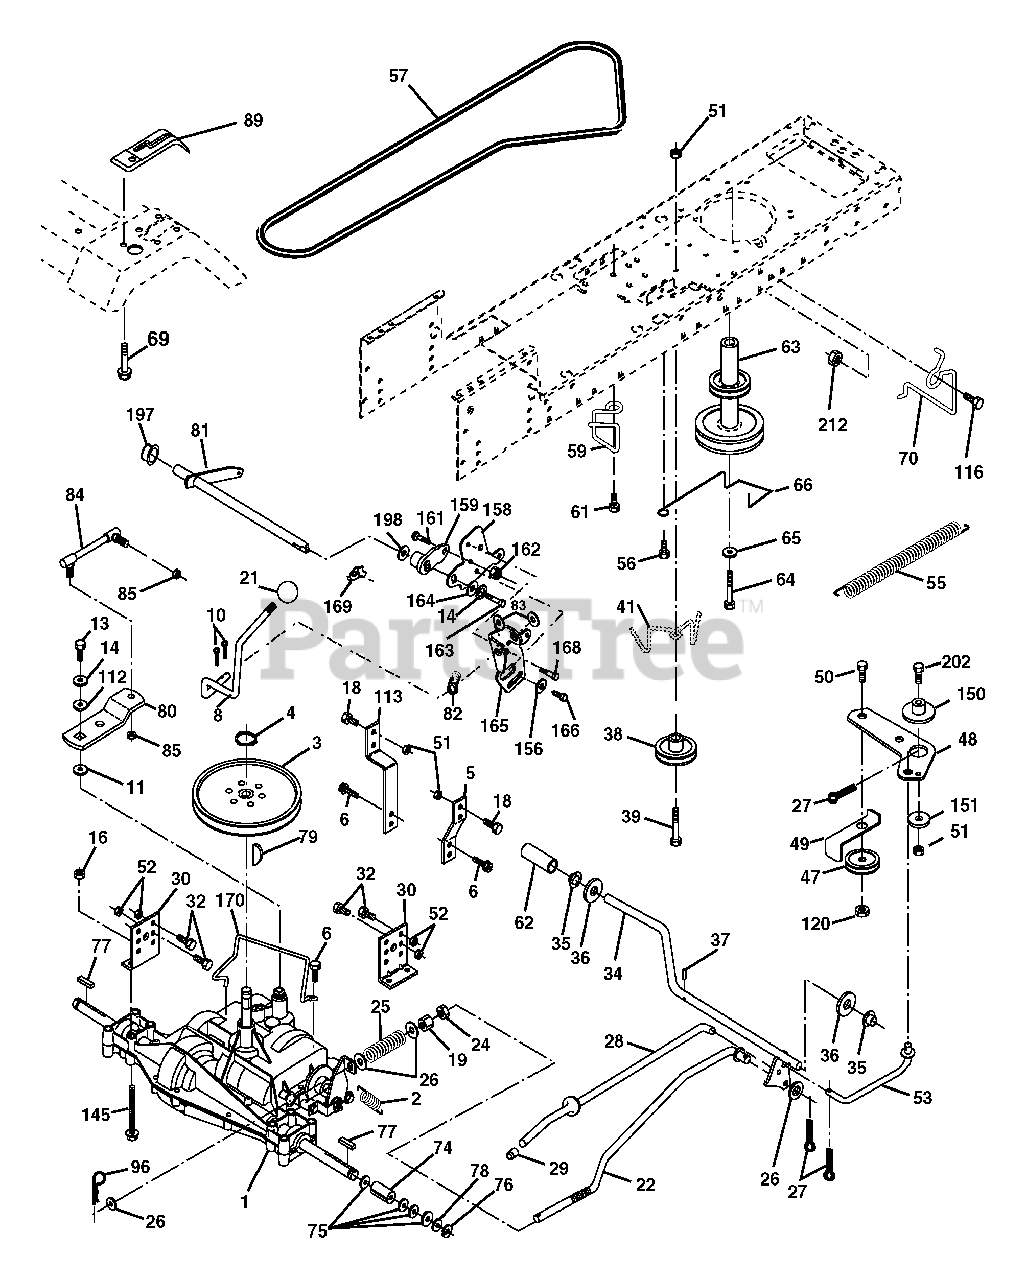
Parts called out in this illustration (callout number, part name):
2	Spring Brake Return
3	Pulley Transaxle
4	Ring Retainer
5	Strap Torque 30 Degrees
6	Screw 5/16-18 x 3/4
8	Rod Shift Fender
10	Pin Cotter 1/8 x 1 CAD
11	Washer Plate Shift
13	Bolt 1/4-28unf Gr. 8 W/Patch
14	Washer Lock Hvy Helical
16	Nut Lock Hex W/Ins. 5/16-18 Unc
18	Bolt Fin Hex 3/8-16 x 1 Gr. 5
19	Nut Lock Hex W/Wsh 3/8-16 Unc
21	Knob
22	Rod, Brake
24	Nut, Hex Jam 3/8-16 Unc
25	Spring, Brake Rod
26	Washer 13/32 x 13/16 Ga.
27	Pin Cotter 1/8 x 3/4 CAD.
28	Rod, Parking Brake
29	Cap, Parking Brake
30	Bracket, Transaxle
32	Bolt Hex Hd 5/16-18 Unc x 3/4
34	Shaft, Foot Pedal
35	Bearing, Nylon
36	Washer
37	Pin, Roll
38	Pulley, Composite, Flat
39	Bolt Fin Hex 3/8-16 x 2-3/4
41	Keeper, Belt Idler
47	Pulley, Idler, V-Groove
48	Bellcrank, Clutch
49	Retainer, Belt
50	Bolt Carr 3/8-16 x 1-1/2
51	Nut Crownlock 3/8-16 Unc
52	Nut, Crownlock 5/16-18 Unc
53	Link, Clutch
55	Spring, Return, Clutch
56	Screw 3/8-16 x 0.875
57	V-Belt
59	Keeper, Center Span
61	Screw . 3/8-16 x .875
62	Cover, Pedal
63	Pulley, Engine
64	Bolt Hex 7/16-20 x 4 Gr. 5
65	Washer
66	Keeper Belt Engine Hydro
69	Screw Hex Wsh Hi-Lo 1/4-1/2 Unc
70	Keeper Belt Engine
74	Spacer
75	Washer 25/32 x 1-1/4 x 16 Ga.
76	E-Ring
77	Key, Square
78	Washer 25/32 x 1-5/8 x 16 Ga.
79	Key Woodruff
80	Arm Shift
81	Shaft Asm Cross Tapered
82	Spring Torsion
83	Washer 17/32 x 3/4 x 16 Ga.
84	Link Transaxle
85	Nut Lock Center 1/4-20
89	Console, Shift
96	Retainer Spring 1" Zinc/Cad
112	Washer 9/32 x 3/4 x 10 Ga.
113	Strap Torque 90 Degrees
116	Bolt Rdhd Sqneck 3/8-16 x 1.25
120	Nut Lock Flg 3/8-16
145	Bolt Hex FLGHD 5/16-18 x Gr. 5
150	Spacer Retainer
151	Washer 13/32 x 2 x 10 Ga.
156	Washer Srrted 5/16 ID x 1.125
158	Bracket Shift Mount
159	Hub Tapered Flange Shift Lt
161	Bolt Rdhd Sqnk 1/4-20 x 3/4 Gr 5
162	Nut Crownlock 1/4-20 Unc
163	Bolt Hex Fin 1/4-20 Unc x 1 Gr 5
164	Washer 5/8 x .281 x 10 Ga
165	Bracket Pivot Lever
166	Screw 5/16-18 x 5/8
168	Bolt Shoulder 5/16-18 x .561
169	Plate Fastening
170	Keeper Belt T/A
197	Nyliner Snap-In 5/8"ID
198	Washer Nyl 7/8 ID x .105" Hyd
202	Bolt Carr Sh 3/8-16 x 1-3/4 Gr.5
212	Nut Hex Flg. Lock
